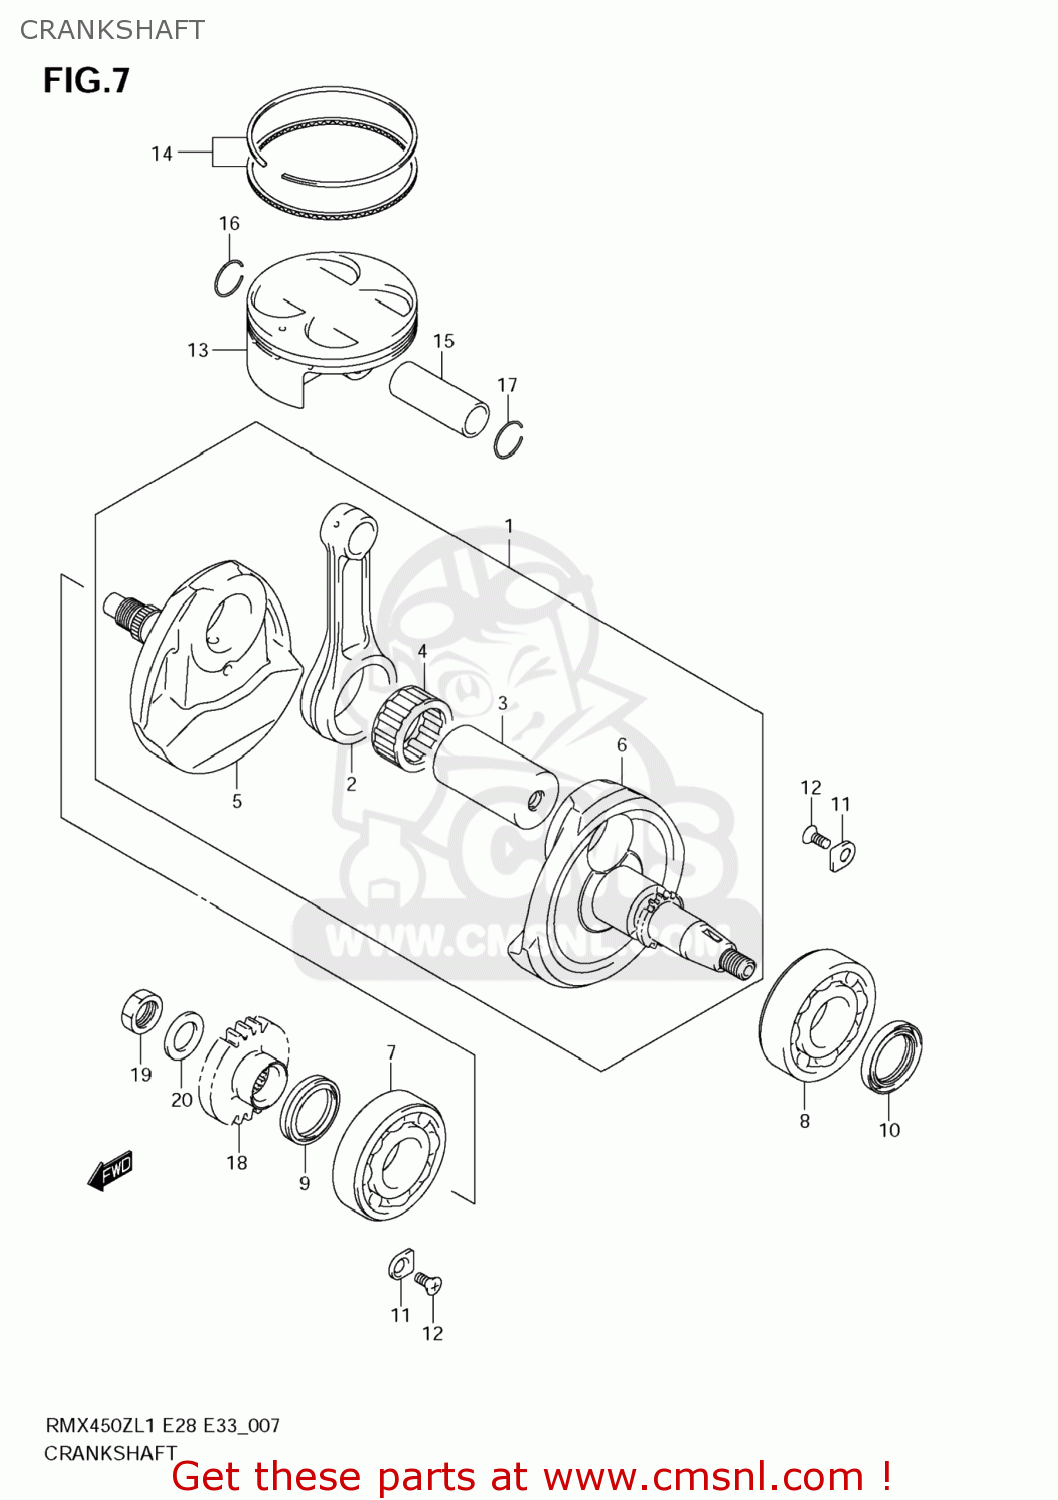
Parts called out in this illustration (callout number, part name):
1	KRUKAS SET
2	CONNECTING ROD ASSY
3	PIN,CRANK
4	BEARING(34X42X20)
5	CRANKSHAFT,R
6	CRANKSHAFT,L
7	BEARING(30X72X19)
8	BEARING(32X75X20)
9	SEAL,OIL(30X40X7)
10	SEAL,OIL(32X47X6)
11	RETAINER,COUNTER BEARING,R
12	SCREW(6X12)
13	PISTON
14	RING SET,PISTON
15	PIN,PISTON
16	RING,SNAP
17	CIRCLIP
18	GEAR,PRIMARY DRIVE
19	NUT
20	WASHER
